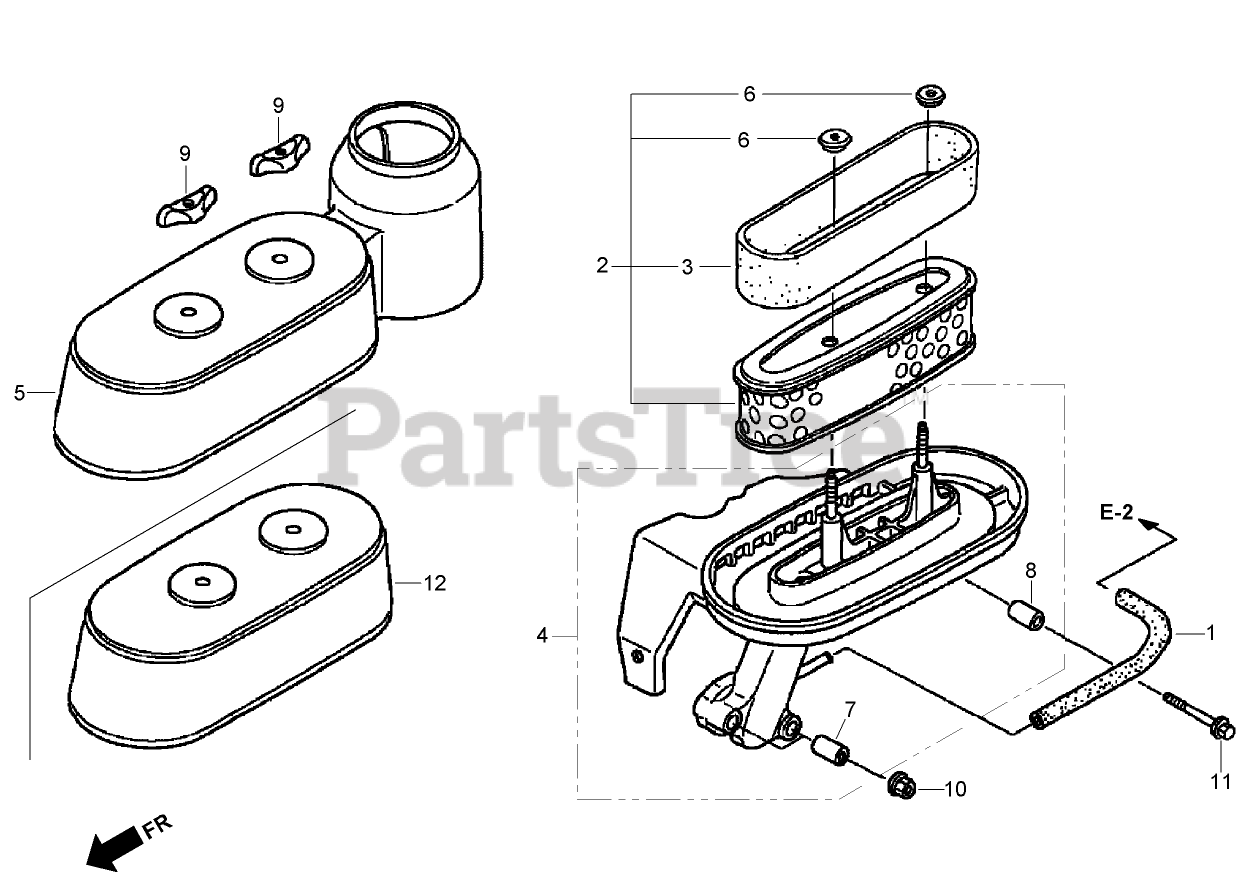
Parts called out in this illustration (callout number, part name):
1	Tube-Breather
2	ELEMENT-CLEANER, AIR
3	FILTER (OUTER)
4	HOUSING-CLEANER, AIR
5	COVER-CLEANER, AIR (Engine Serial No. Up To 1036455)
6	GROMMET-CLEANER, AIR
7	COLLAR-CLEANER, AIR
8	COLLAR B-CLEANER, AIR
9	NUT-CLEANER, AIR
10	NUT-FLANGE (6 mm)
11	BOLT-FLANGE (6X35)
12	COVER-CLEANER, AIR (Engine Serial No. From 1036456)
